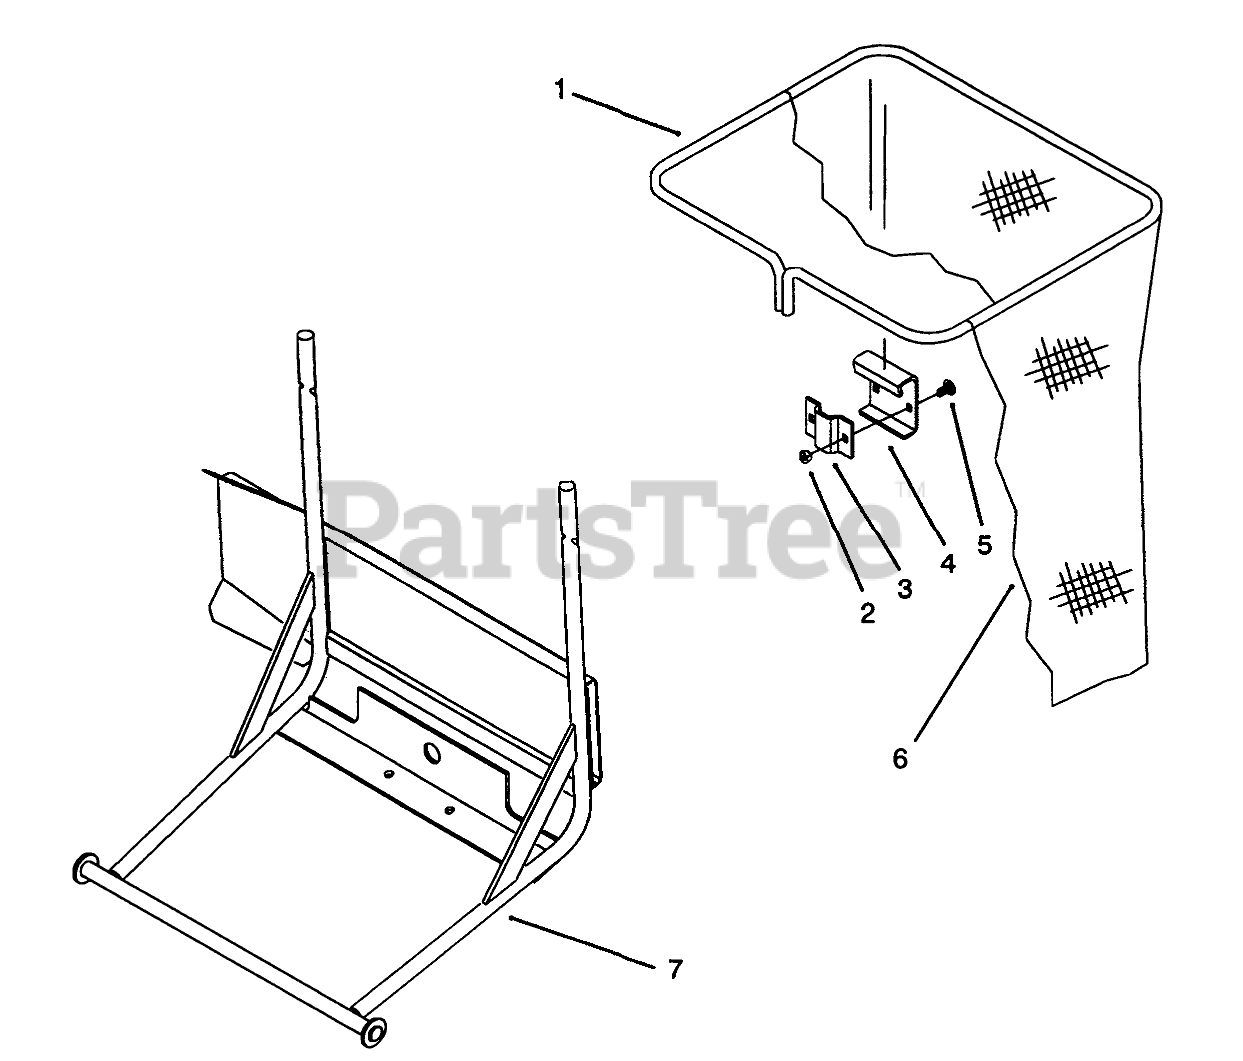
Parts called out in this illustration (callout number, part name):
1	Bag Frame
2	NUT-LOCK, NI
3	Clamp
4	Bag Hanger
5	BOLT-CARR
6	Bag
7	WLDMT-BAGGER RODS B
